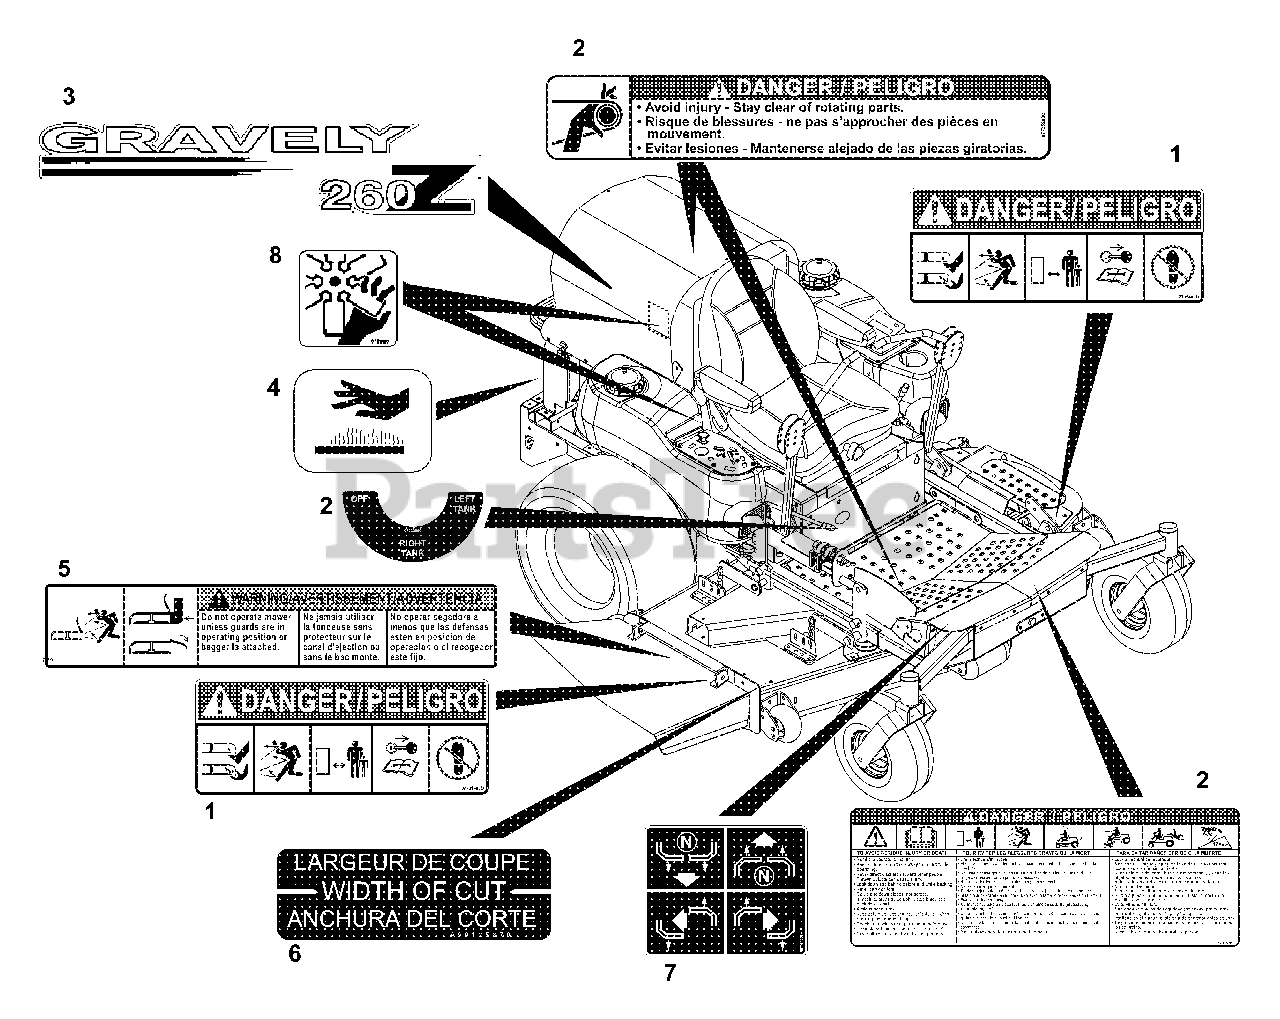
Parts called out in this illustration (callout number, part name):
1	Decal, Mower Pan Head Danger
2	Set, Decal-Common Danger/Fuel
3	Decal, PM-260Z Hood (073, 075, 318, 319)
3	Decal, PM-272Z Hood (074, 076)
4	Decal, Hot Surface
5	Decal, Warning
6	Decal, Width of Cut
7	Decal, Instructional
8	Decal, Danger Fan
